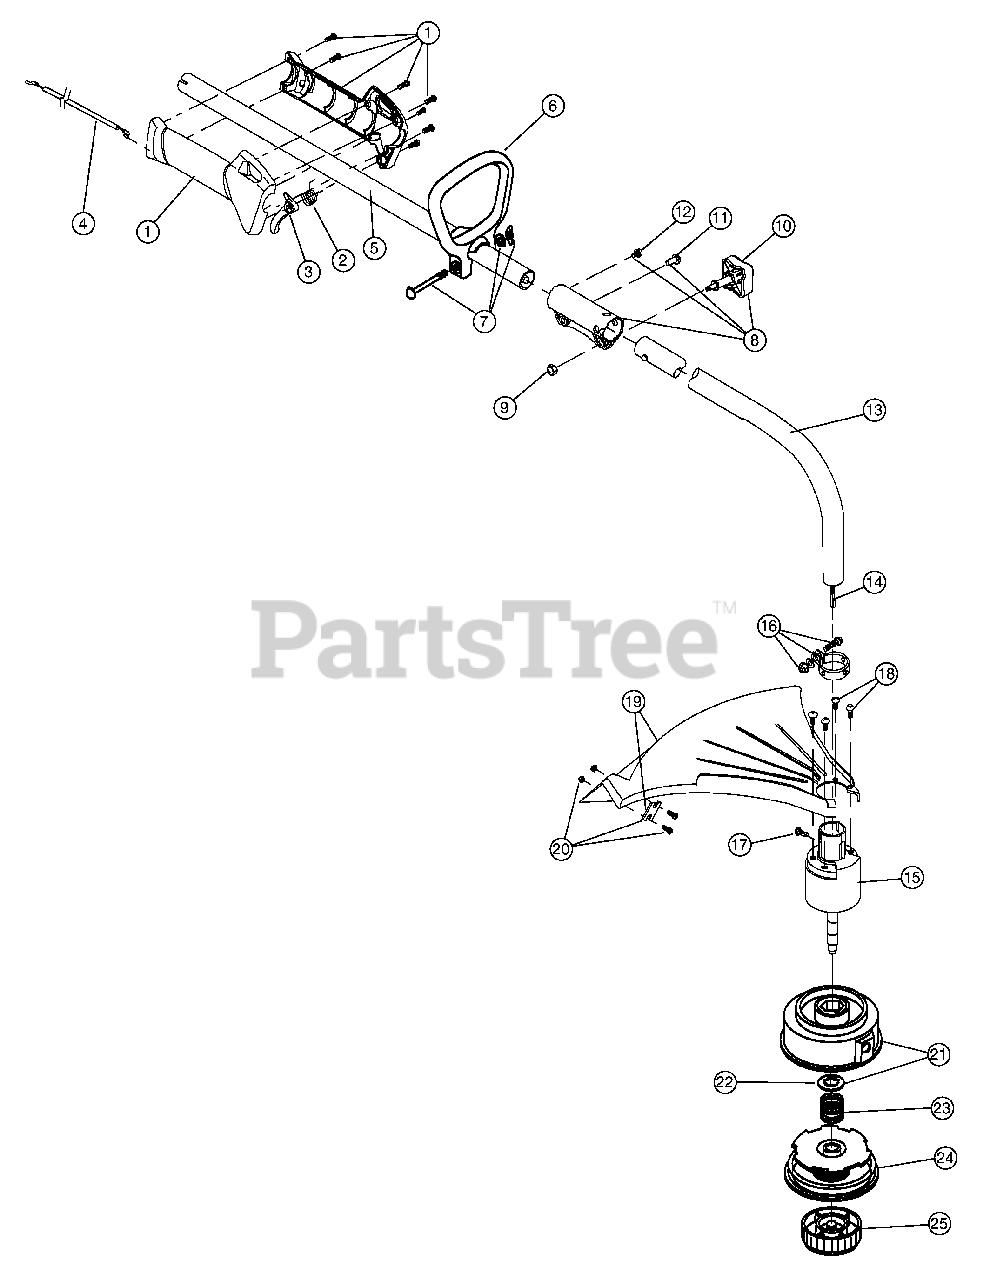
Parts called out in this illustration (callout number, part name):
1	Throttle Housing & Trigger Assembly
2	Throttle Trigger Spring
3	Throttle Trigger
4	Throttle Cable Assembly
5	Upper Drive Shaft Housing Assembly
6	D-Handle Assembly
7	D-Handle Hardware
8	Click Link Coupler Assembly
10	Knob
13	Lower Drive Shaft Housing Assembly
14	Lower Flexible Drive Shaft
15	Bushing Housing Assembly
16	Lower Clamp Assembly
17	Anti-Rotation Screw
18	Guard Mounting Screw Assembly
19	Guard and Blade Assembly
20	Blade Assembly
21	Outer Spool Assembly
22	Retainer
24	Inner Reel
25	Bump Head Knob Assembly
